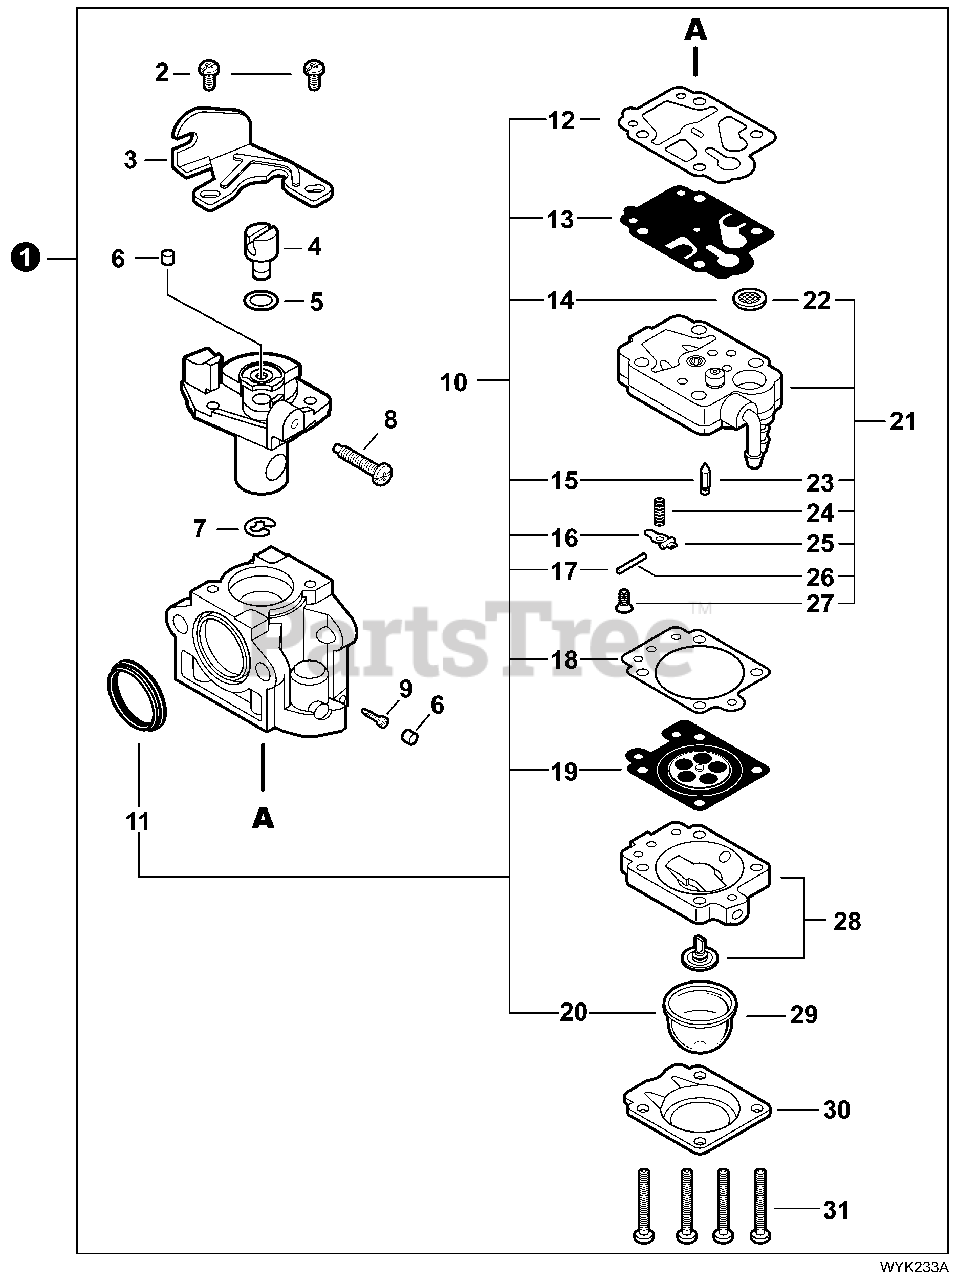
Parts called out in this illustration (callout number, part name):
1	CARBURETOR -- WYK-233A
3	BRACKET, CABLE
6	CAP, LIMITER
7	RING, RETAINING
8	SCREW, IDLE ADJUST
9	NEEDLE - HIGH SPEED
10	REPAIR KIT
11	RING, PACKING
12	GASKET, PUMP
13	DIAPHRAGM, PUMP
14	STRAINER
15	VALVE, INLET NEEDLE
16	LEVER, METERING
17	PIN, METERING LEVER
18	GASKET, DIAPHRAGM
19	DIAPHRAGM, METERING
20	BULB, PURGE
21	PUMP BODY ASY
22	STRAINER
23	VALVE, INLET NEEDLE
24	SPRING, METERING LEVER
25	LEVER, METERING
26	PIN, METERING LEVER
27	SCREW, METERING LEVER PIN
28	PURGE BASE ASY
29	BULB, PURGE
30	RETAINER, PURGE BULB
31	SCREW, PUMP COVER
